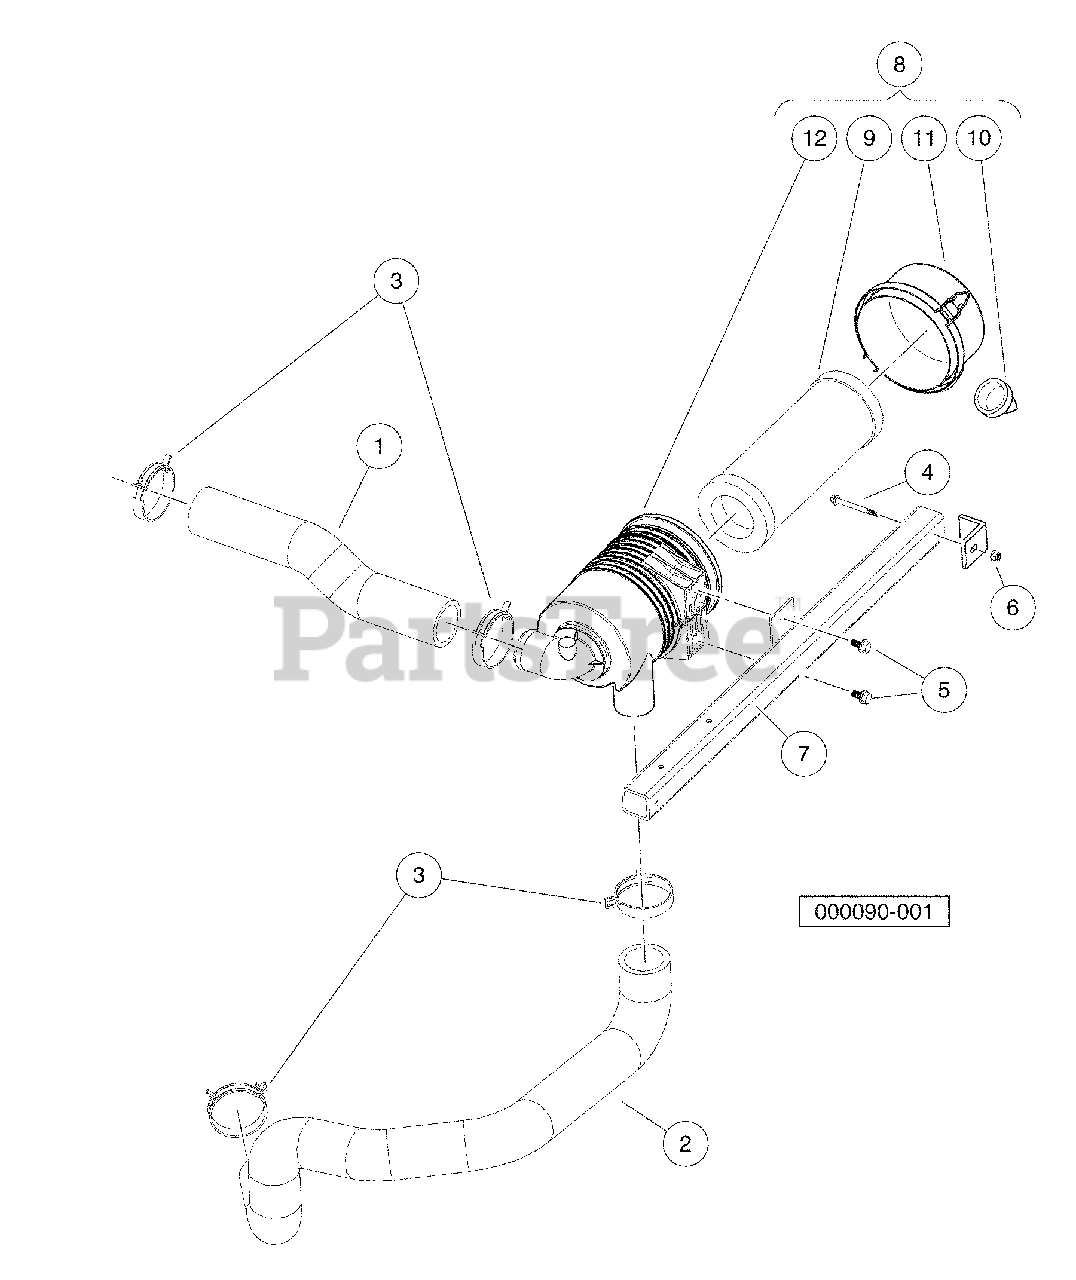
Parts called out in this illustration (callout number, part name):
1	Hose, Intake, GX620
2	Hose, Intake, Primary
3	Clamp, Hose, Ctb 64mm
4	Bolt, M 6 X 1.0 X 65 Hex, Flange, Head, Black
5	Bolt Flanged Head, M8 X1.25x 16 with Loctite
6	Nut Flg, M6 X 1.0 Nylon
7	Weldment, Support, Air Cleaner
8	Filter, Air, Canister, W/labe
9	Element, Filter, Air, 5 In
10	Valve, Evacuator, Filter Air
11	Cap, Latch Lock, Filter, Air
12	Body, Canister, Filter, Air
